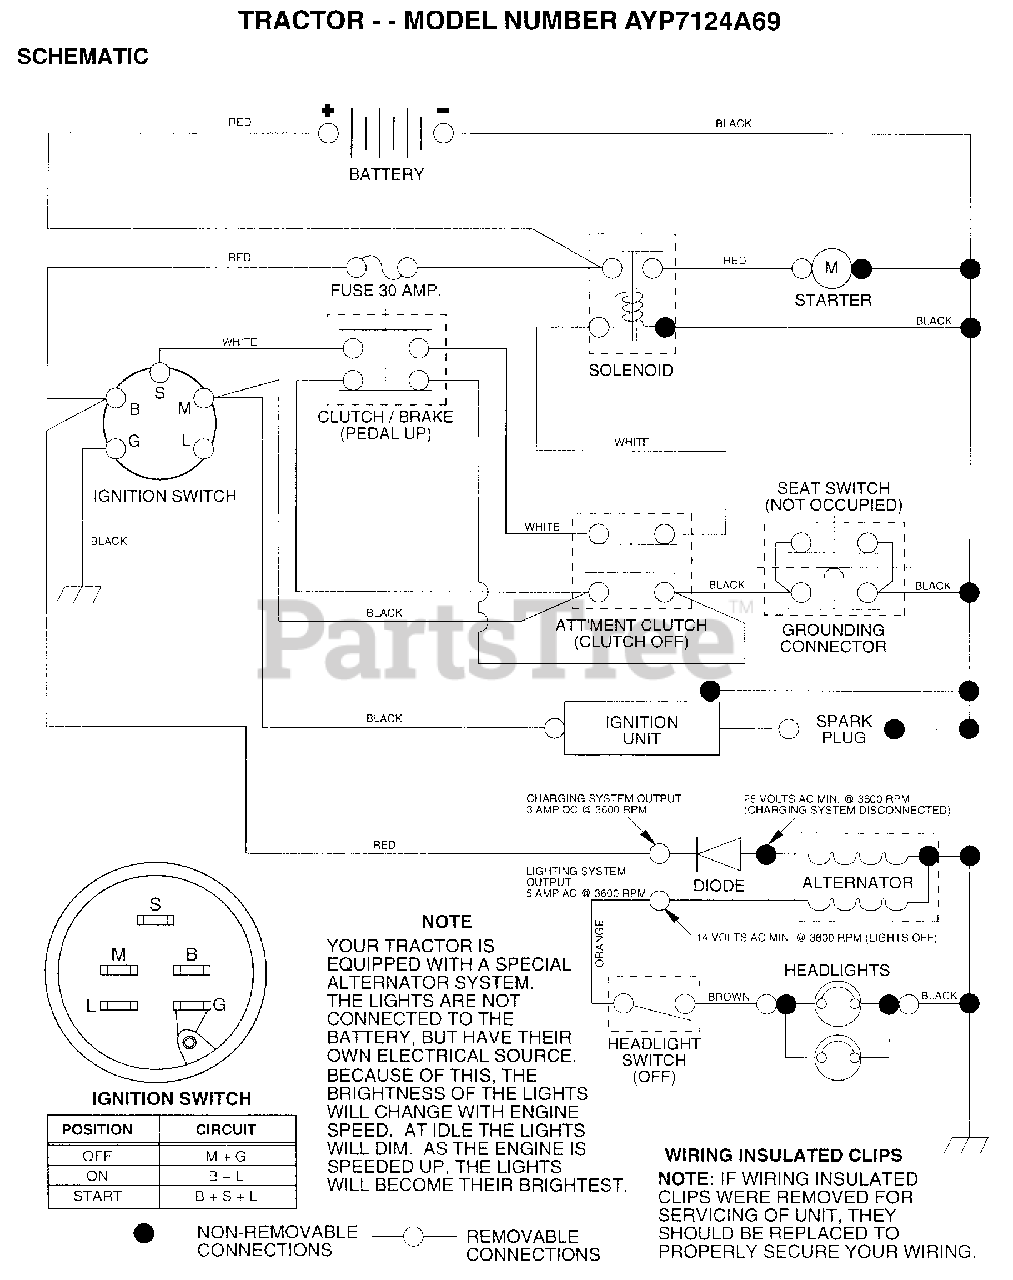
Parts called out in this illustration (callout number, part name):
2	BOLT LT
3	WASHER
7	TUBE T
9	HOSE CLAMP T
15	FASTNER.SNAP-IN
20	NUT
21	"HARNESS,LIGHT SOC"
22	HEADLAMP BULB
24	"CABLE T, BATTERY"
25	CABLE.BTRY.6GA.RD
26	FUSE HYT
28	CABLE T
29	SWITCH SEAT
30	SWITCH IGN 4POS
31	NUT IGNITION
32	COVER KEY SWITCH
33	KEY
35	BRACKET LT
36	SCREW
38	BRACKET SWITCH IN
39	SWITCH INTERLOCKT
40	HARNESS.IGNITION
41	BOLT.HX.1/4-20
44	NUT HXKEP 1/4X20
46	PROTECTION LOOP
48	ADAPTER AMMETER
52	PROTECTION LOOP
70	HARNESS.ENGINE
